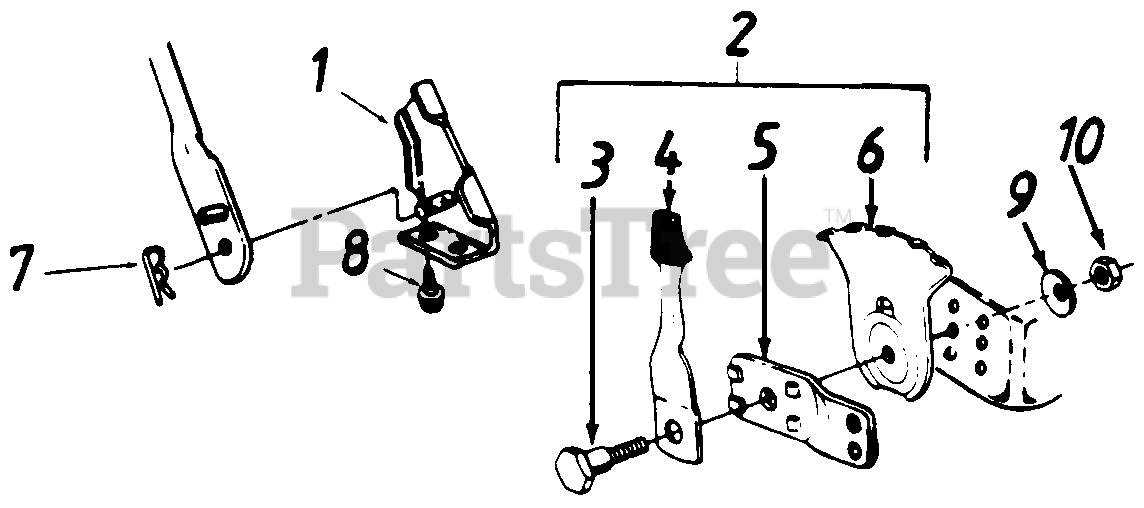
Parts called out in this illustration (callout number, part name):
1	Handle Mount Brkt. Ass'y.- L.H.
3	Shouldor Bolt .500" Dia. x .357
4	Spring Lever Ass'y. w/Knob
5	Pivot Bar
6	Index Plate
7	Hairpin Cotter
8	Hex Wash. Hd. Self-Tap Scr. 5/16-18 x .50" Lg.
9	Belleville Wash. .39 I.D. x 1.4 O.D.
10	Hex Nut 3/8-16 Thd.
